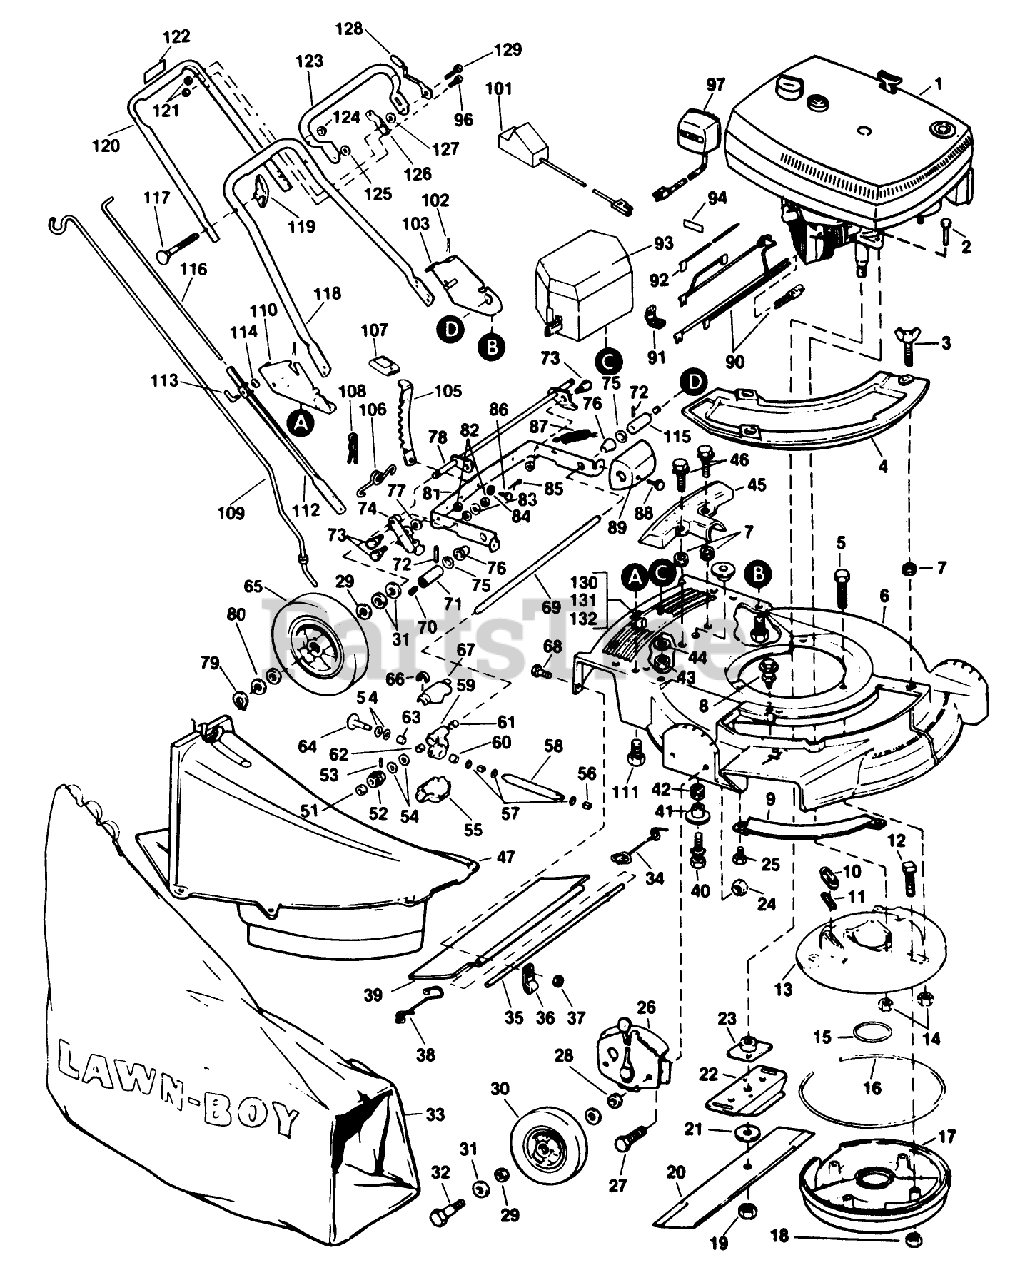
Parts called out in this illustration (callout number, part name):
1	See Page 24 for Engine, Magneto and Carburetor Parts List. See Note #2at bottom of this page.
2	BOLT F
3	WING SCREW LAWRE
5	SCREW V
9	BAR-TOE
10	SLEEVE
11	GASKET S
12	SCREW
14	NUT-LOCK F
16	Gasket Muffler (outside)
18	LOCKNUT E
19	NUT-BLADE
21	WASHER
23	PLATE AND COLLAR ASM
24	NUT
28	WASHER WROUGHT
29	WASHER
30	WHEEL & TIRE KIT
31	SPACER
32	BOLT WHEEL
33	ORD LB 89802 WHOLE GOODS
34	SPRIG T/SHLD ASOC
35	ROD 21" ADVANCE
36	CLAMP ROD KMC
38	SPRING;TRAILING SHIELD RH
41	SPACER ECK PRES
42	GROMMET
44	WASHER
45	COVER
46	SCREW SEMS TRM HEX HD
51	WASHER
53	ROLL PIN
54	THRUST WASHER
56	BUSHING
57	O Ring
63	NEEDLE BEARING
67	GEAR COVER UPPER
69	DRIVE SHFT TAG AY
70	GREASE PLUG
72	PIN
73	BOLT RB&W
75	WASHER S
77	WASHER S
78	Axle Assembly
79	RET RING
80	SPACER
82	STOP NUT
84	WASHER SPRING LAR
86	PIN
87	SPRING
89	GUARD
102	HAIR PIN
105	LEVER
106	SPRING N.A.S
107	KNOB
109	ROD GRASSBAG
111	SCREW
116	ROD CONTROL
119	NUT-WING
120	HANDLE
125	WASHER M
128	KNOB & SPRING
129	BOLT RB&W
